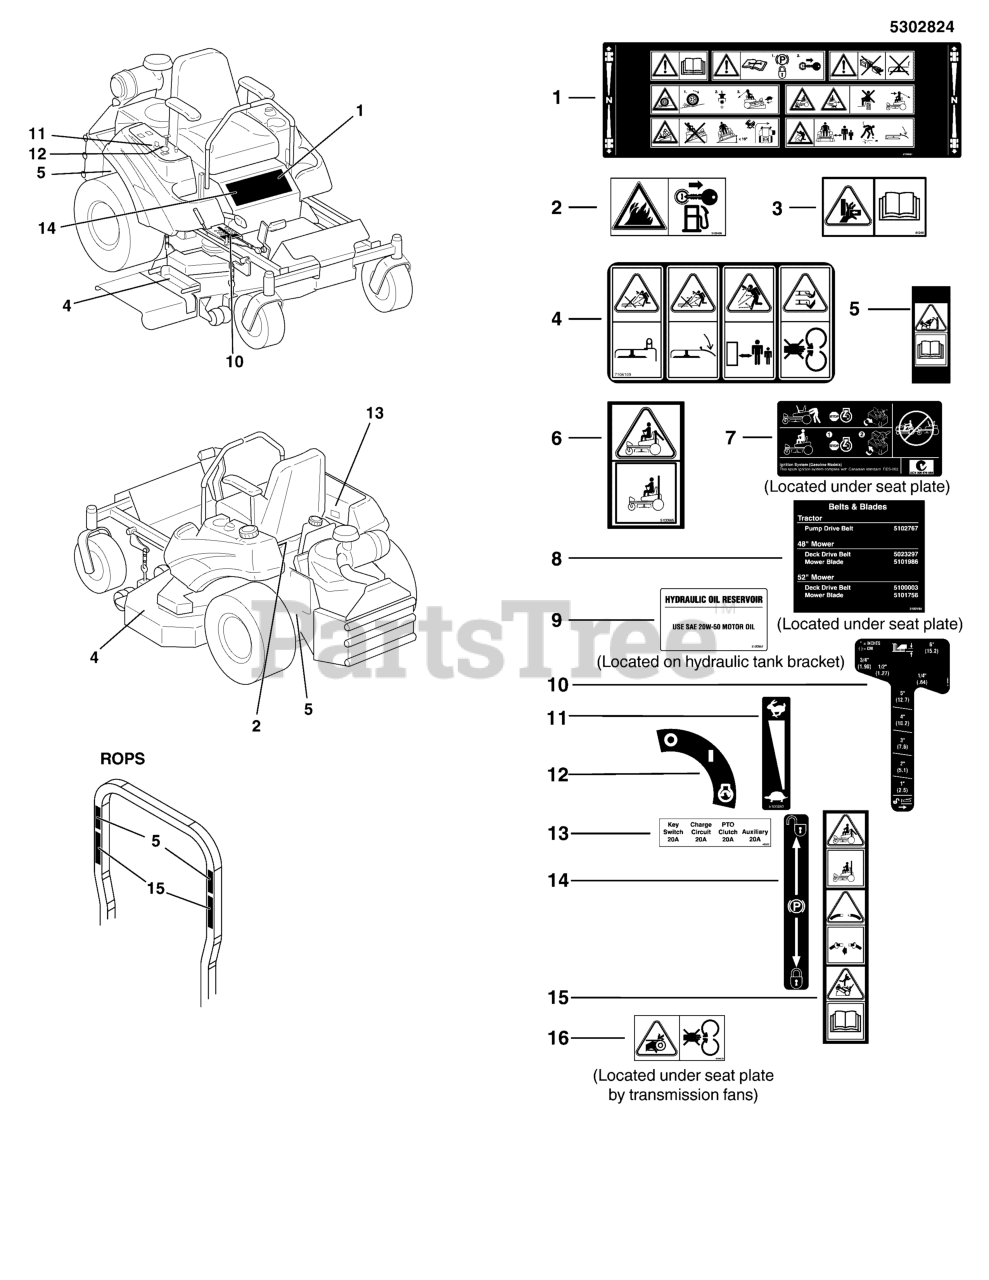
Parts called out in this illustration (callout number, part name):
1	DECAL, MAIN SAFETY, ANSI CE
2	DECAL, FIRE ANSI EXPORT
3	DECAL, PINCH POINT, CE
4	DECAL, DISCHARGE SAFETY, EXPORT
5	DECAL, SAFETY, CE ROPS, OBS
6	DECAL, WARNING, ROLL BAR, CE
7	DECAL, TRANSAXLE RELEASE, S200XT
8	DECAL, BELT & BLADE, IS150XT-52
9	DECAL, HYDRAULIC OIL, SAE 20W50
10	DECAL-HEIGHT CITATION
11	DECAL, THROTTLE CONTROL
12	DECAL, IGNITION SWITCH
13	DECAL, FUSE LOCATION
14	DECAL, PARKING BRAKE SYMBOLS
15	DECAL, SAFETY, CE ROPS
16	DECAL, CE DANGER
